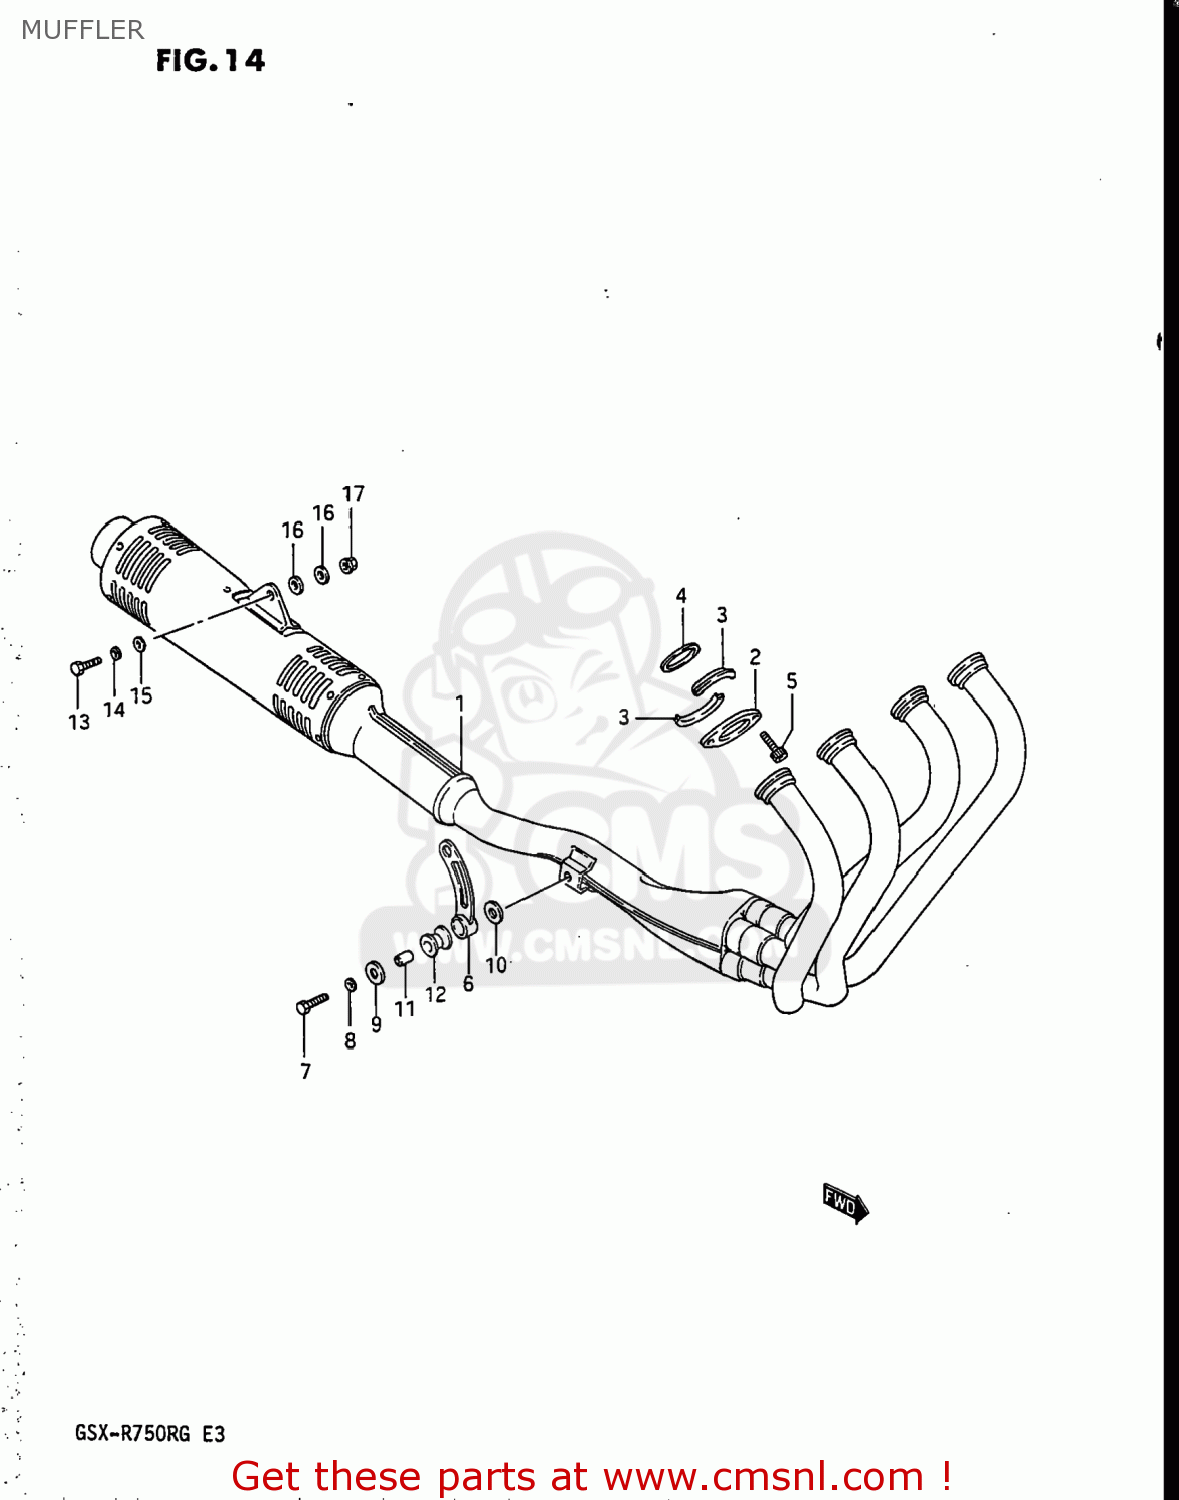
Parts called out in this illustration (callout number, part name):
1	MUFFLER ASSEMBLY
2	CLAMP,EXHAUST PIPE
3	PLATE,EXHAUST PIPE
4	GASKET,EXHAUST PIPE (NAS)
5	BOLT
6	DAMPER,MUFFLER SUPPORT
7	BOLT 8X35
8	WASHER
9	WASHER
10	WASHER (8.5X20X1.6)
11	SPACER (8.6X12X17.5)
12	CUSHION
13	BOLT
14	WASHER,LOCK
15	WASHER 10MM
16	WASHER
17	NUT
